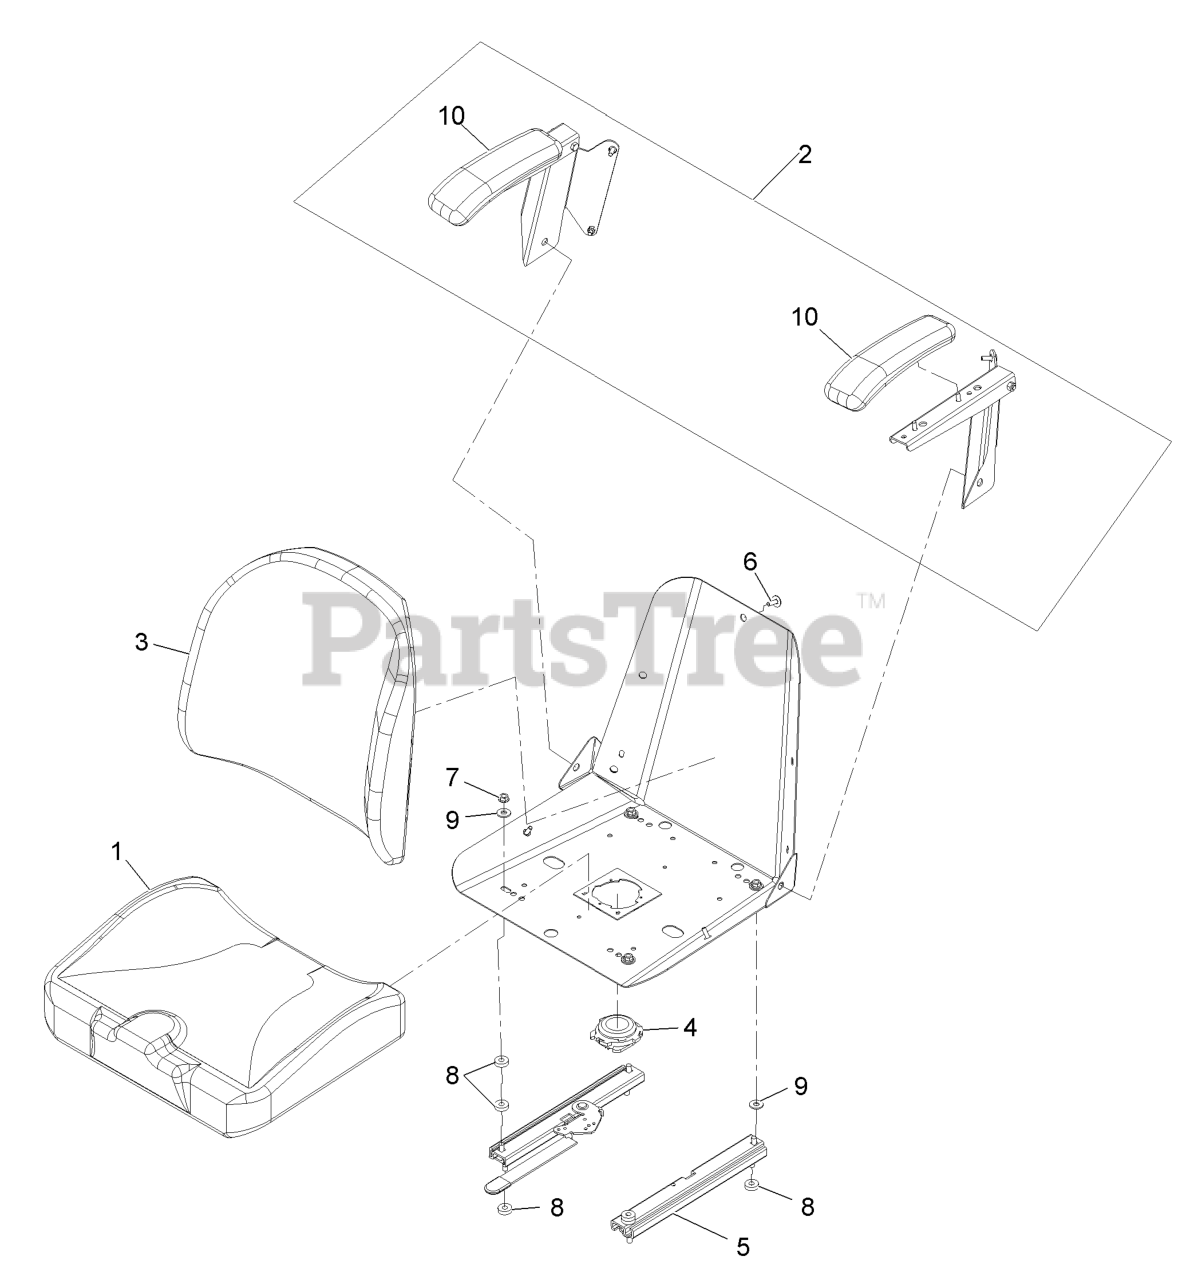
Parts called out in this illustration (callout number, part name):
1	CUSHION,SEAT BOTTOM
2	ARMREST KIT
3	CUSHION,SEAT BACK
4	SWITCH-SEAT
5	TRACK-SEAT
6	BOLT-SEAT
9	WASHER-FLAT
10	CUSHION-REST, ARM
